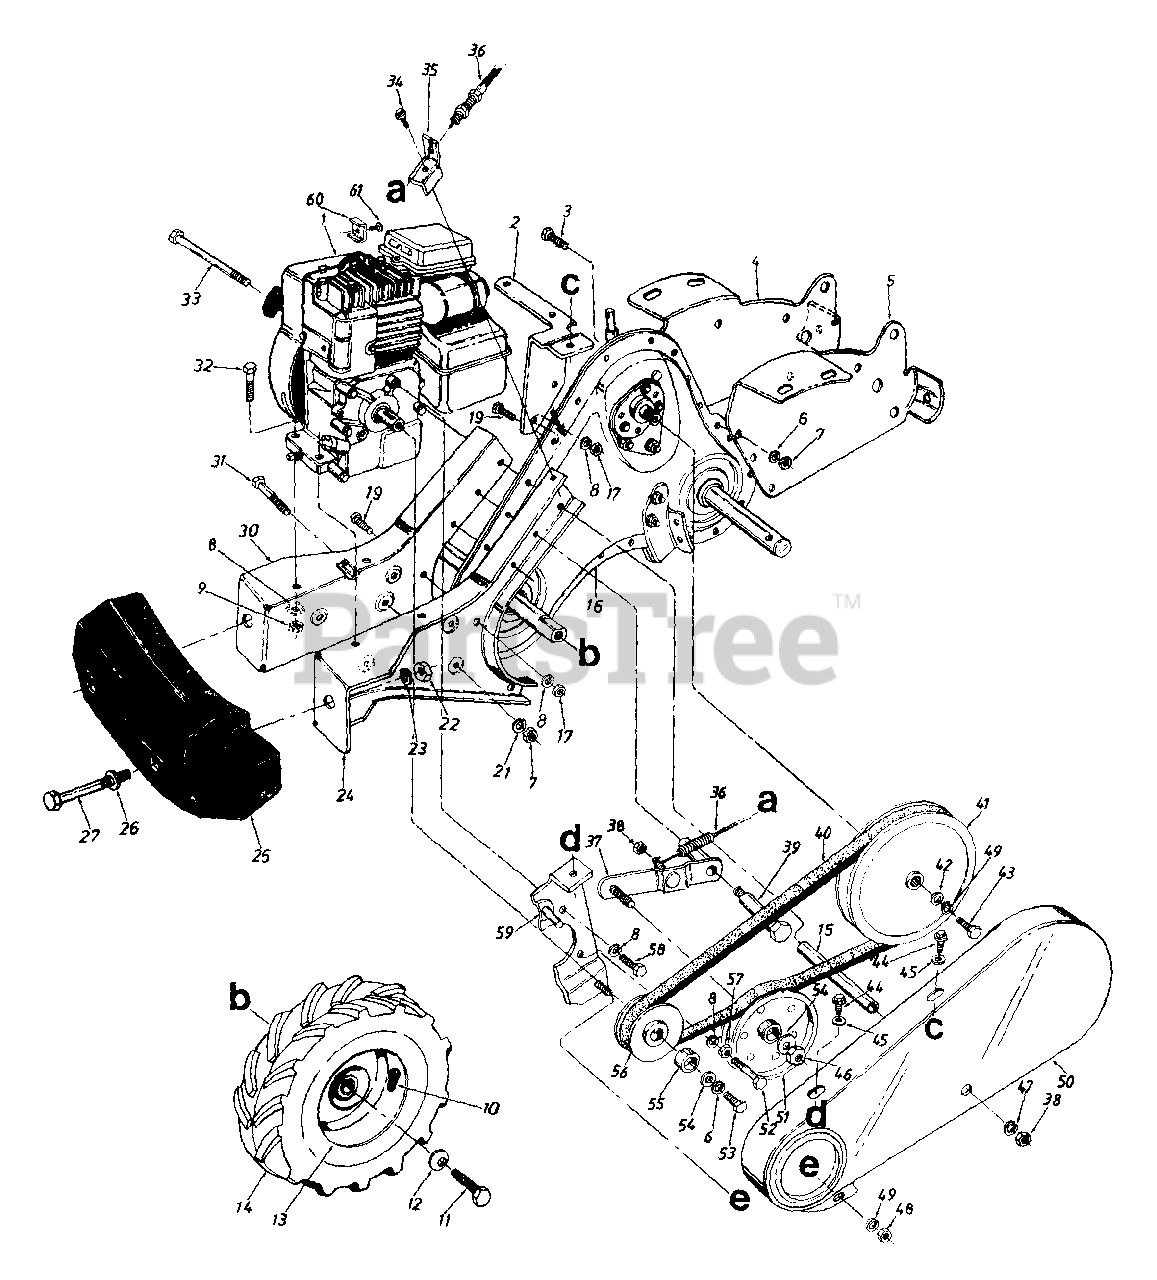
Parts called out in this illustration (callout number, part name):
1	Engine
7	Hex Nut 3/8-16 Thd.
8	L-Wash. 5/16" I.D.
9	Hex Nut 5/16-18" Thd.
10	Air Valve
11	Hex Bolt 5/16-24 x .62" Lg.
12	Bell-Wash..345" I.D. x .88"
13	Wheel Rim Ass'y. Only
14	L.H. Wheel Ass'y. Comp.
16	Transmission Comp.
17	Hex Nut 5/16-18 Thd.
19	Hex Bolt 5/16-18 x .75" Lg.
21	L-Wash. 3/8" I.D.- H.D.
22	Hex Nut 1/2-13 Thd.
23	L-Wash. 1/2" I.D.
26	Fl-Wash. .510" I.D. x 1.0"
27	Hex Bolt 1/2-13 x 5.00" Lg.
32	Hex Bolt 5/16-18 x 1.50"
33	Hex Bolt 5/16-18 x 4.75" Lg.- Gr. 2
34	Hex Wash. TT-Tap Scr. 5/16-18 x .62" Lg.
35	Bracket Clutch Cable
36	Clutch Control Cable 53" Lg.
39	Shld. Bolt .500" Dia. x 2.27"
40	"V"-Belt
41	"V"-Pulley Split 5/8" I.D.
42	Fl-Wash. 1/4" I.D. x .93" O.D.
43	Hex Bolt 1/4-28 x .75" Lg.
44	Hex Wash. Hd. S-Tap Scr. 1/4-20 x .50" Lg.
45	Fl-Wash. .281" I.D. x .625"
46	Hex Cent. L-Nut 3/8-24 Thd.
47	Fl-Wash. 5/16" I.D.
48	Hex Nut 1/4-20 Thd.
49	L-Wash. 1/4" I.D.
51	Fl-Idler w/Flanges 3.75" O.D.
52	Hex Bolt 5/16-24 x 1.75"
53	Hex Bolt 3/8-24 x 1.00" Lg.
54	Fl-Wash. 3/8" I.D. x 1.00"
55	Spacer .758" I.D. x .990"
56	Engine Pulley
57	Hex Nut 5/16-24 Thd.
58	Hex Bolt 5/16-24 x .62" Lg.
61	Hex Sems Scr. #10-32 x .62"
